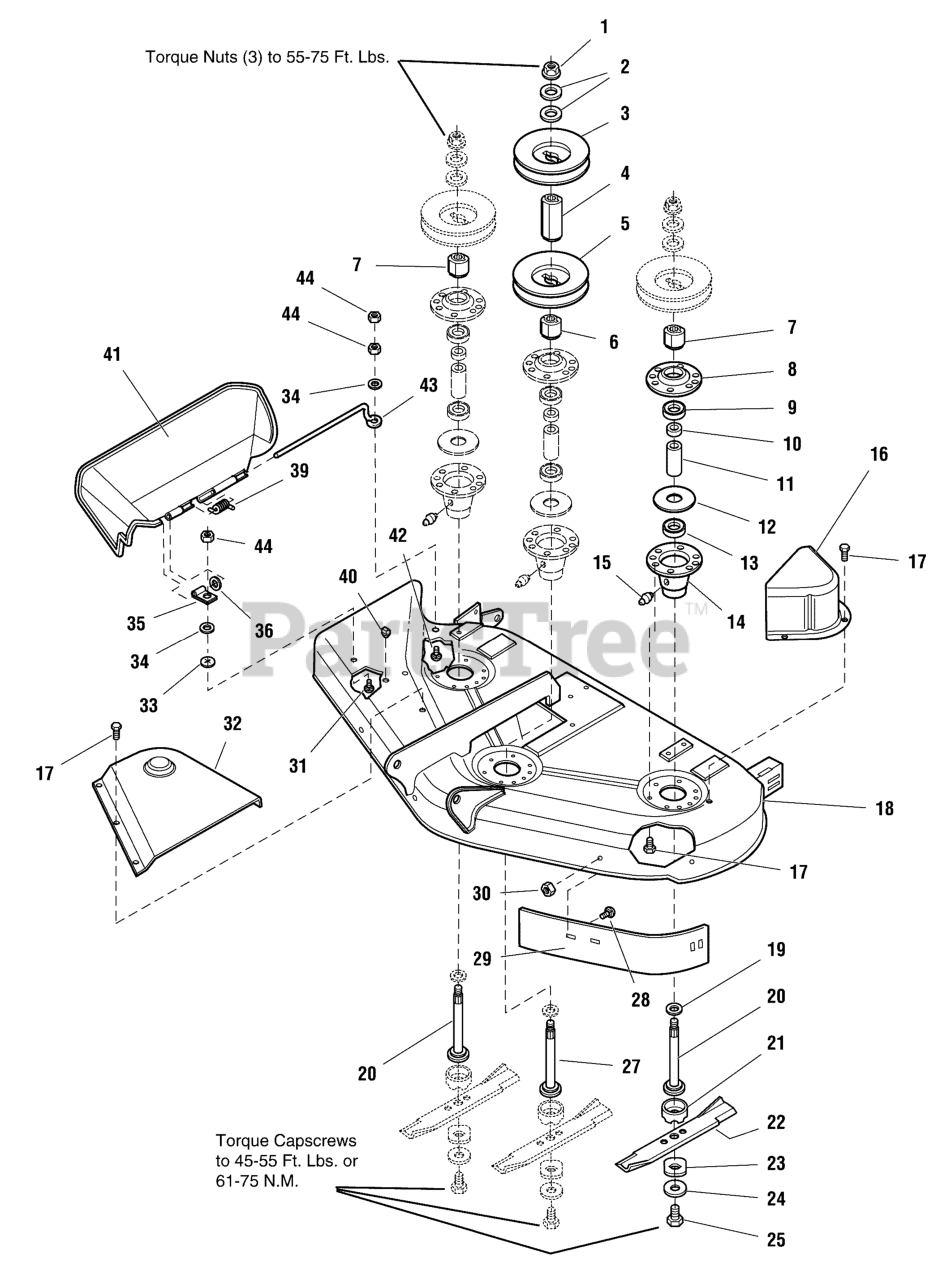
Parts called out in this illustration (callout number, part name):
1	NUT, Hex Plange Non-Locking, 9/16-18
2	WASHER, Bellville .56ID x 1.34 OD x .05T
4	HUB, Spacer, 2-13/32
6	HUB, 35/64
7	HUB, Serated, 35/64
8	HOUSING, Arbor Top
9	BEARING, Ball
10	SPACER, Bearing Sleeve
11	SPACER, Tube
12	GASKET, Foam
13	BEARING, Ball
14	HOUSING ASSEMBLY, Arbor Bottom, w/Lube Fitting
15	FITTING, Lube, 1/4 Drive
16	COVER, Arbor
17	CAPSCREW, Hex, Washer Head, Taptite, 5/16-18 x 3/4, G5
18	HOUSING ASSEMBLY, 44" Mower Deck
19	WASHER, Cup
20	SHAFT, Arbor with Extruded Washers (short)
21	SHIELD, Grass, Lower Arbor
22	BLADE, Mower 44"
23	WASHER, Hex
24	WASHER, Spring, 3/8
25	CAPSCREW, Hex Head, 7/16-14 x 1-1/4, G8
27	SHAFT, Arbor with Extruded Washers (Long)
28	CARRIAGE BOLT, 5/16-18 x 3/4, G5
29	BAFFLE, Blowout, Short
30	NUT, Hex Flange Whiz Lock, 5/16-18
31	CARRIAGE BOLT, 1/4-20 x 7/8, G5
32	COVER, Arbor
33	NUT, Push
34	WASHER, 1/4
35	CLAMP, Wire, 5/16 Diameter
36	WASHER, 5/16
39	Sring, Torsion
40	PLUG, Button
41	DEFLECTOR, Discharge
42	CARRIAGE BOLT, 1/4-20 x 1-1/2
43	ROD, Deflector
44	SPACER, .66 X 7/8 X 1 1/4
